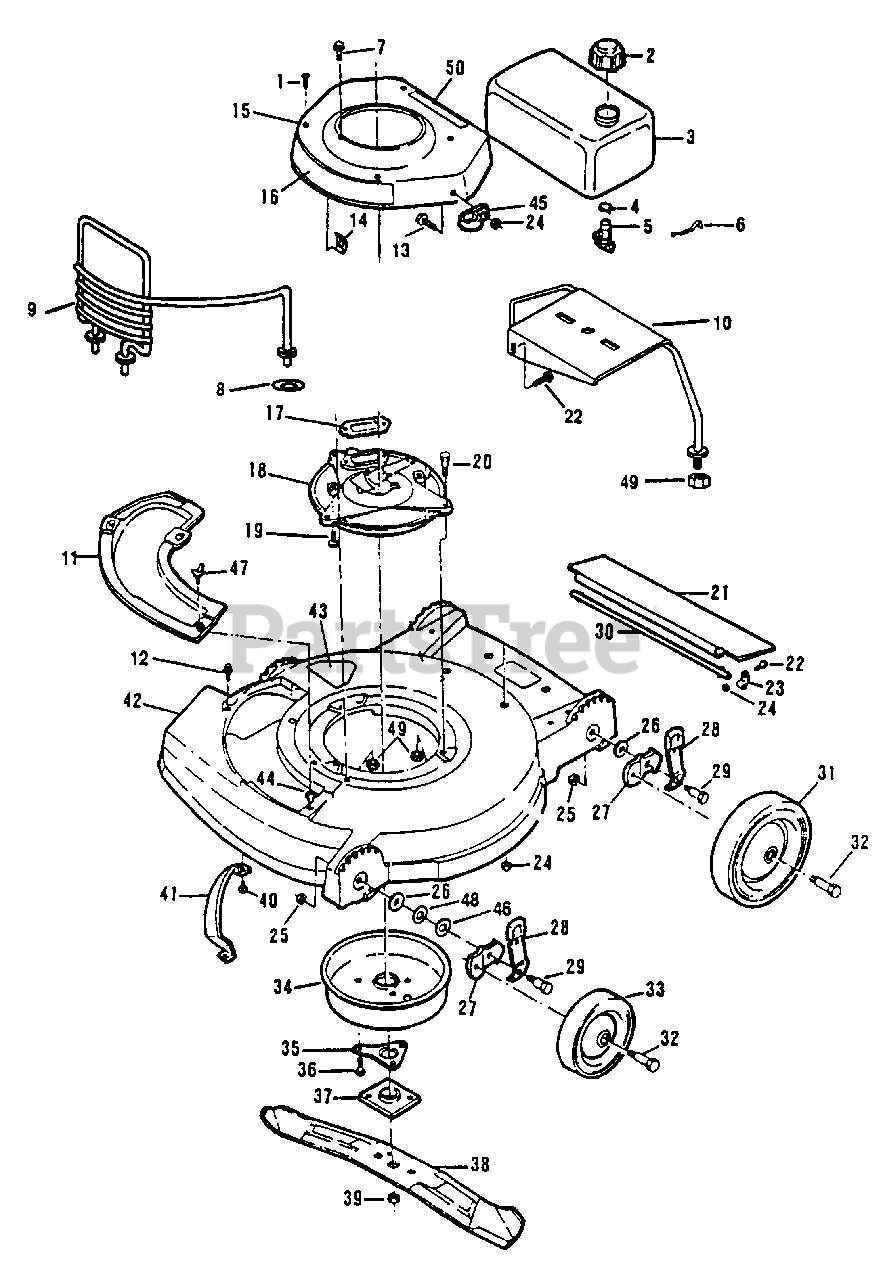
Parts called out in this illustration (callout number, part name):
1	Screw-Shroud to Base
2	Fuel Cap Assembly
3	Fuel Tank
4	Clamp-Valve to Tank
5	Shut-Off Valve & Screen
6	Spring-Fuel Tank Mounting
7	Screw-Starter
8	Washer
9	Engine Guard
10	Fuel Tank Bracket
11	Cover Plate
12	Screw-SEMS-Cover Plate
13	Screw-Clamp to Shroud
14	Retainer-Applique
15	Shroud
16	Applique
17	Gasket-Exhaust
18	Muffler Plate
19	Screw-Muffler Plate to Block
20	Screw-Muffler Plate to Housing
21	Trailing Shield
22	Screw
23	Clamp-Shield Rod
24	Locknut
25	Locknut-Wheel Brkt. to Housing
26	Washer-Wheel Brkt. to Housing
27	Wheel Height Adjust Bracket
28	Height Adjust Knob & Spring
29	Shoulder Bolt
30	Trailing Shield Rod
31	Rear Wheel-8"
32	Wheel Bolt
33	Front Wheel-6"
34	Muffler Cover
35	Crankshaft Support Plate
36	Screw-Plate to Muffler Cover
37	Collar and Plate
38	21" Blade
39	Nut-Blade
40	Screw-Toe Bar To Housing
41	Toe Bar
42	Housing Assembly (Inc. 43-44)
43	Decal-Blade Contact Warning
44	Grommet
45	Clamp
46	Washer-Shim
47	Wing Screw
48	Washer-Shim
49	Nut
50	Decal-Fuel Mixture
